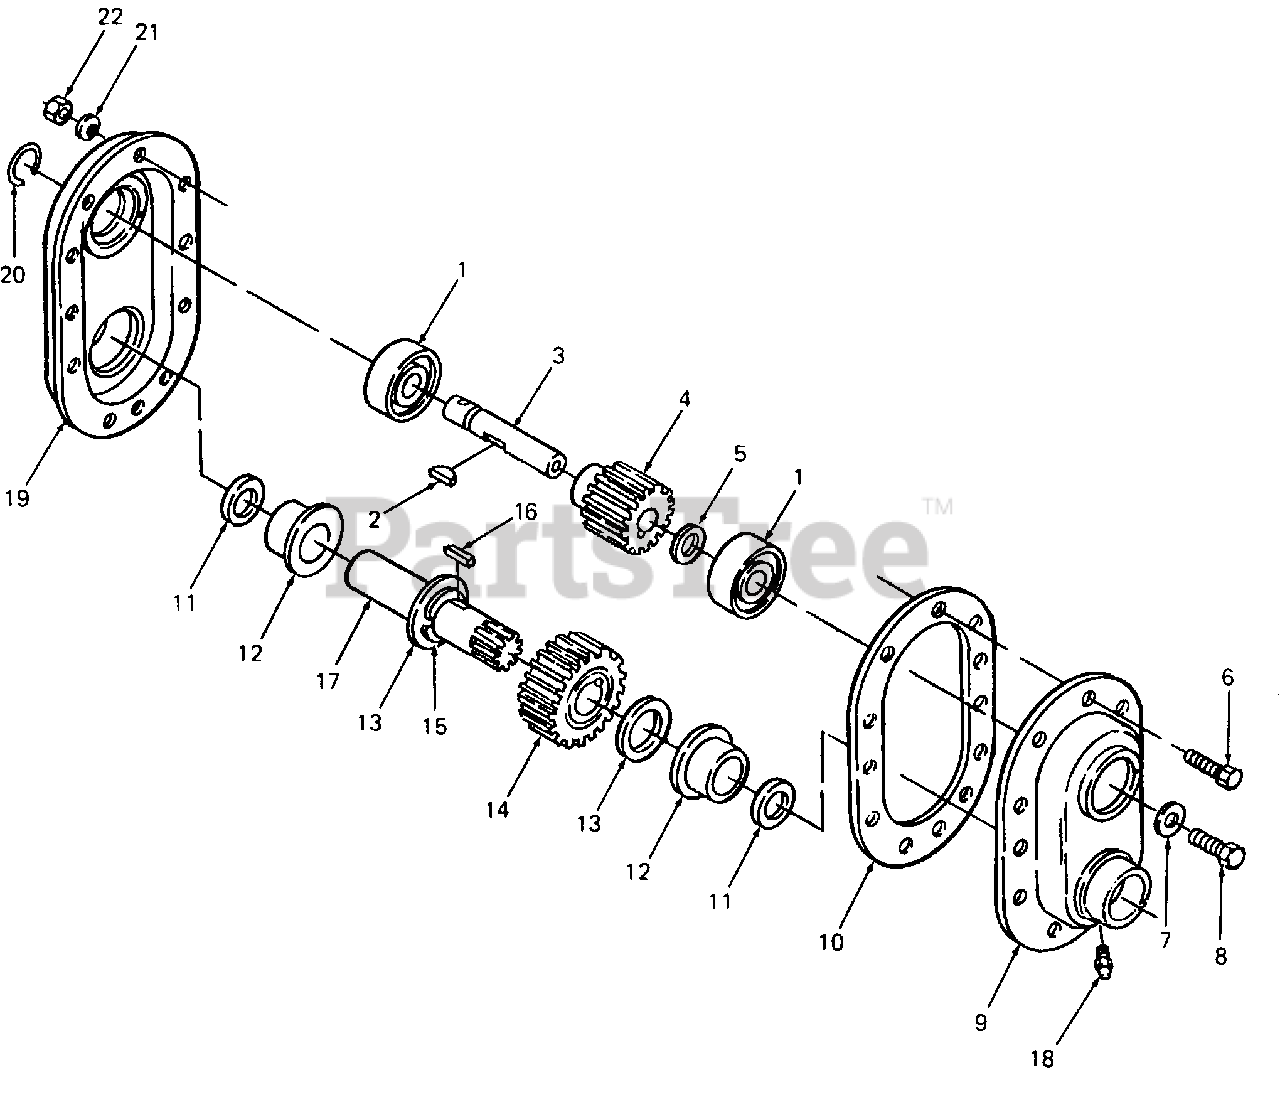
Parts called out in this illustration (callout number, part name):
1	Bearing, Ball
2	Key, Woodruff, 1/4 X 3/4 HDN
3	Shaft, Input
4	Spur - Gear, 15T
5	Washer, Flat, 1.0 X 1.625 X .090 Thk
6	Screw, Hex Cap, 1/4-28 X 1.0 Lg GR5
7	Washer, Flat, .406 X 1.25 X .157 Thk HDN
8	Screw, Hex Patch, 3/8-24 X 1.0 Lg GR5
9	Housing Half - RH
11	Seal, Oil, 1.25 ID X 1.75 OD
12	Bearing, Flange, 1.252 ID
13	Washer, Flat, 1.25 X 2.0 X .060 Thk
14	Spur - Gear, 28T
15	Ring, Snap
16	Key, Hi-Pro, 1/4 X 7/8
17	Shaft, Splined Output
18	Fitting, Gear
19	Housing Half - LH
20	Ring, Snap
21	Washer, Spring, .270 X .51 X .030 Thk
22	Nut, Hex, 1/4-28
